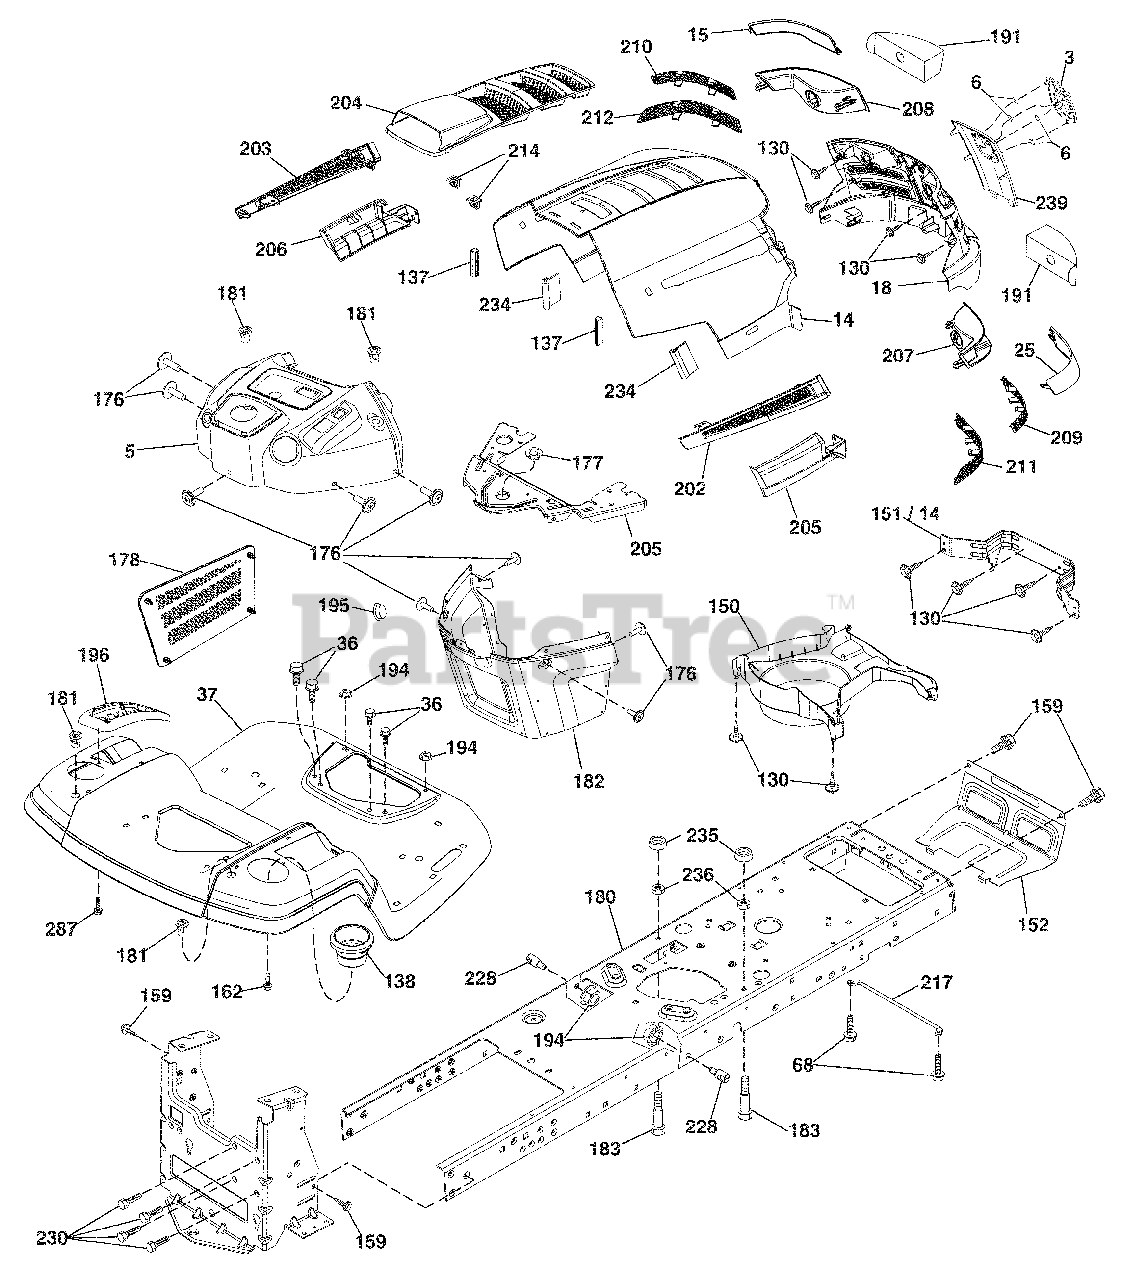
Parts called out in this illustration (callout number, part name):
3	Logo
14	Hood
18	Grille/Lens Asm.
36	Screw 5/16-18 x 3/4
37	Fender
68	Screw Thdrol 5/16-18 x 1/2
130	Screw #10 x 0.750
137	Bumper Dash
138	Cupholder
151	Bracket Pivot Hood
152	Shield Browning
159	Screw 3/8-16 x 3/4
175	Crossmember
176	Screw 10-24 x 5/8
177	Bushing Steering
178	Cargo Net Asm.
180	Chassis
181	Bushing Mtg. Fender Crgo
182	Dash Lower
183	Bolt Fin Hex 5/16-18 unc x 1-1/4
194	Nut Lock Hex Flange 5/16-18
195	Plug Hole Dash Lower
196	Console Asm. Deck Lift
202	Vent Side Hood RH
203	Vent Side Hood LH
204	Vent Top Hood
205	Skirt Hood Side RH
206	Skirt Hood Side LH
209	Insert Hex Top RH
210	Insert Hex Top Lh
211	Insert Hex Bottom RH
212	Insert Hex Bottom LH
214	Clip Retainer Tinner
228	Stud Fastner
230	Bolt Shoulder 5/16-18
234	Bumper Hood
235	Spacer Fender
236	Nut Lock 5/16-18 UNC
287	Screw 1/4-20 x 3/8
